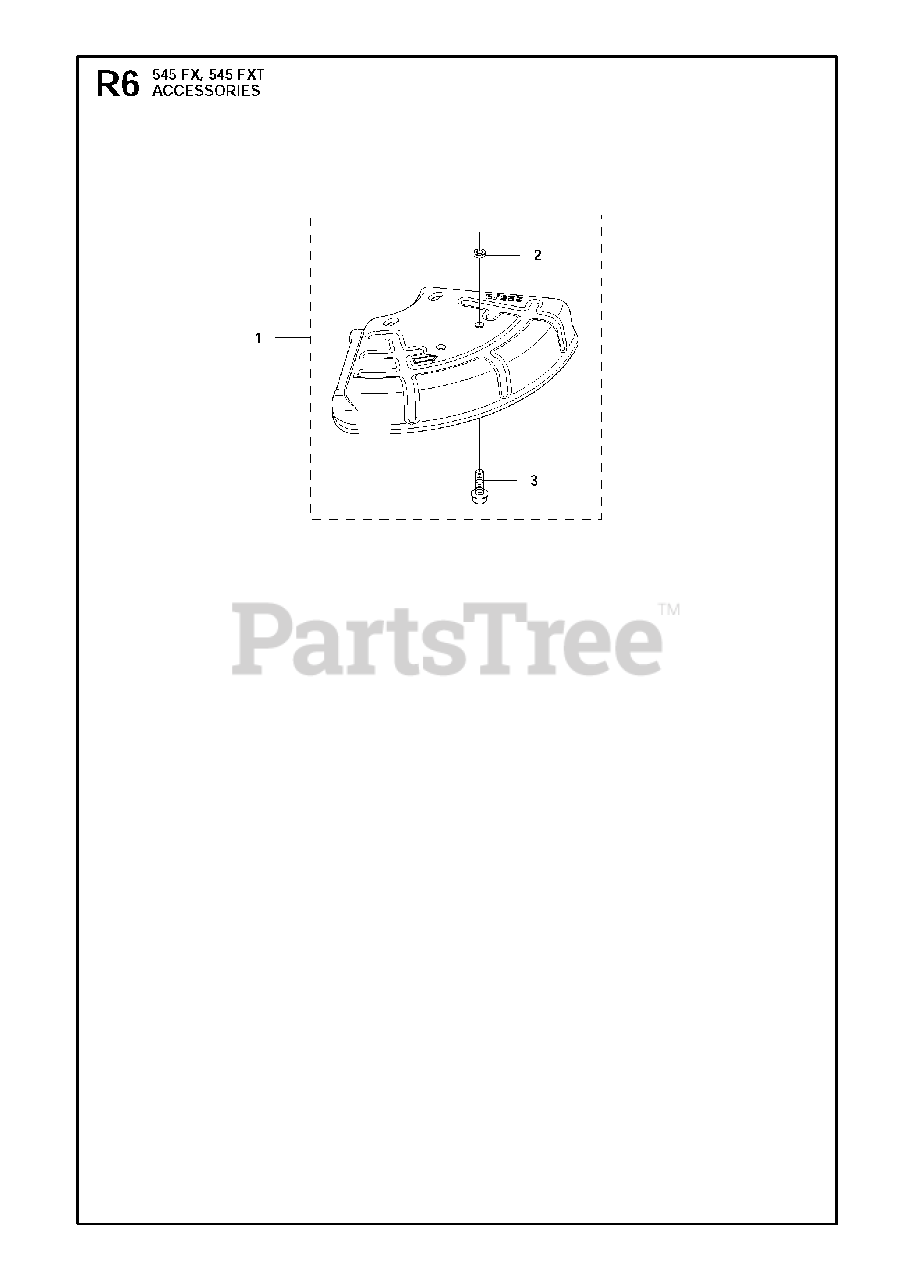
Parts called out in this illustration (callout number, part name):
1	BLADE GUARD
2	LOCKING NUT
3	SCREW
